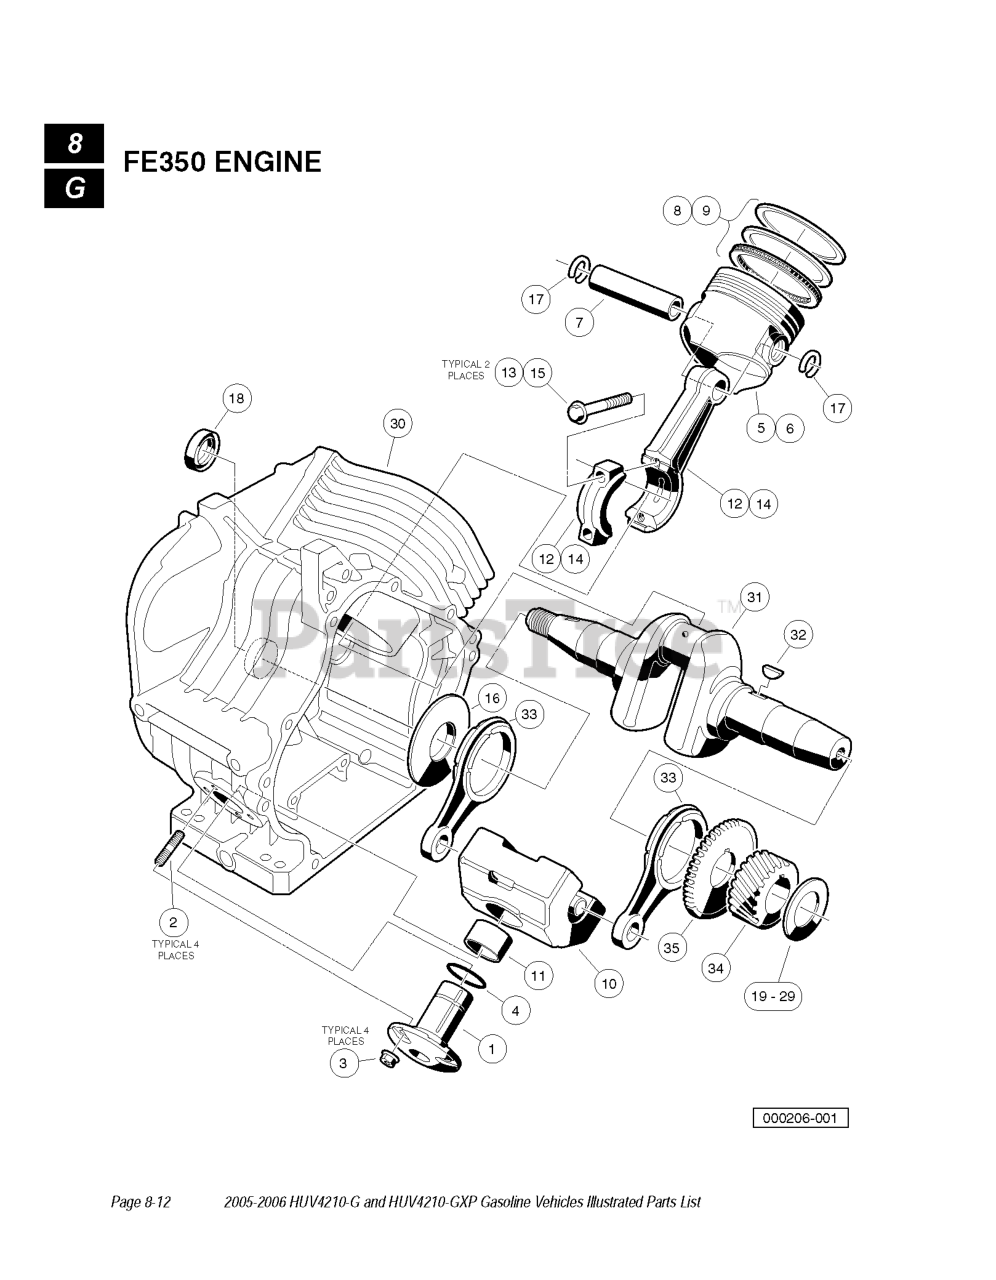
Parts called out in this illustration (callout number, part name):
1	SHAFT, GUIDE, COUNTER-BALANCE
2	STUD, 6X14
5	PISTON - ENGINE STD
6	PISTON, .50MM OVERSIZE ENGINE
7	PIN PISTON
8	RING SET, STANDARD PISTON
9	RING SET PISTON .50MM OVERSIZE
11	BEARING - PLAIN
12	ROD ASSY CONNECTING ROD STD
14	ROD ASSY CON ROD .5MM U/S
17	RING - SNAP
18	SEAL - OIL
19	SHIM JCRANKSHAFT FE350
20	SHIM CRANKSHAFT FE350
21	SHIM CRANKSHAFT FE350
22	SHIM CRANKSHAFT FE350
23	SHIM CRANKSHAFT FE350
24	SHIM CRANKSHAFT FE350
25	SHIM CRANKSHAFT FE350
26	SHIM CRANKSHAFT FE350
27	SHIM CRANKSHAFT FE350
28	SHIM CRANKSHAFT FE350
29	SHIM CRANKSHAFT FE350
30	CRANKCASE COMPLETE, FE350 CW
31	SPUR GEAR
